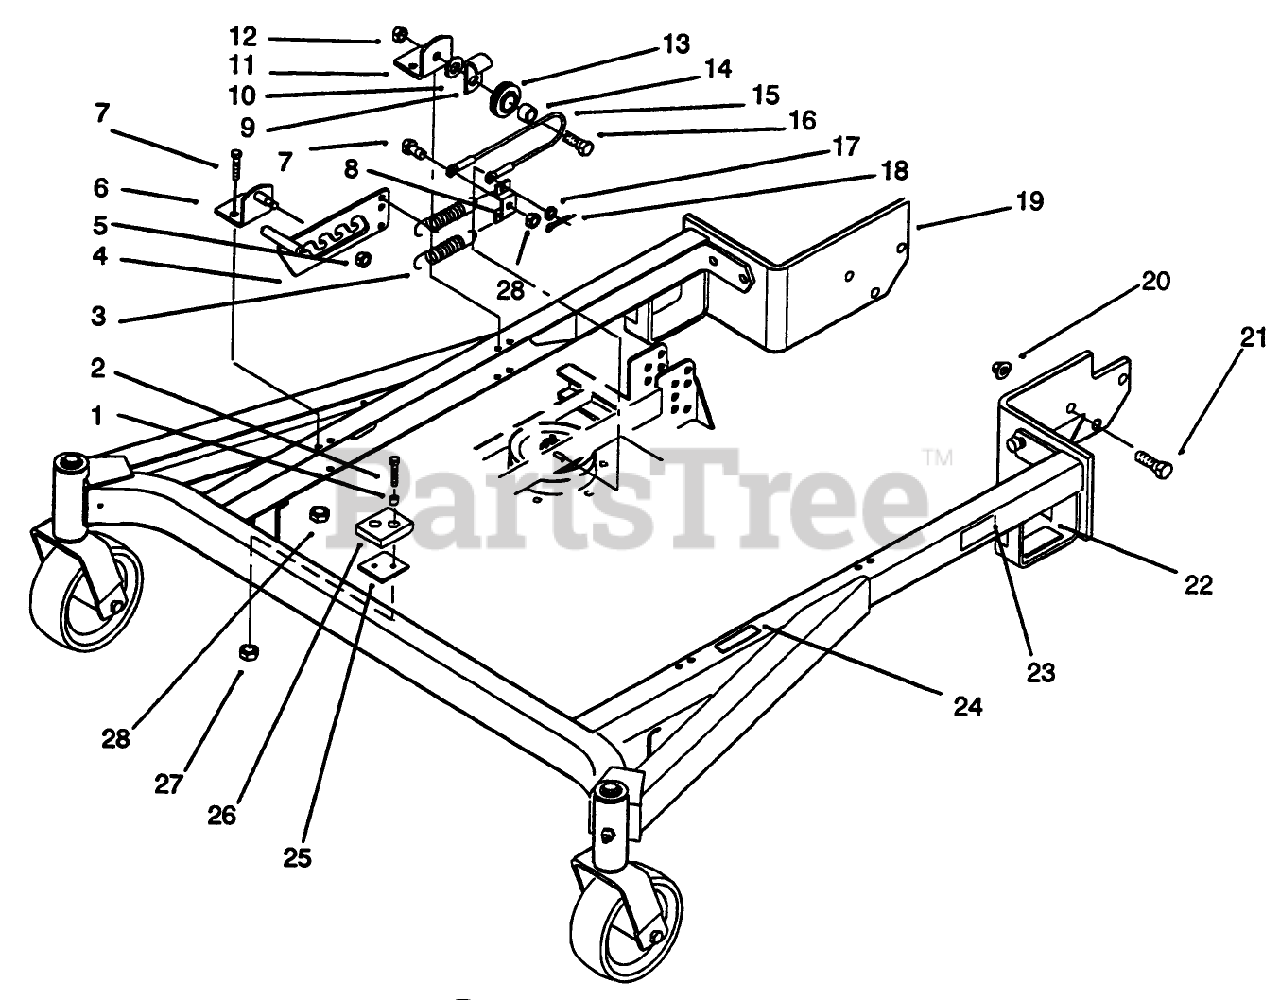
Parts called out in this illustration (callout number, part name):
1	SPACER
3	EXTENSION SPRING
4	Control-Tension
5	NUT-HF
6	Bracket-Control
7	SCREW-HH
8	SPRING BRACKET
9	CABLE RETAINER
10	THRUST WASHER
11	Bracket-Pulley
12	NUT-LOCK, NI
13	Pulley Assembly (Incl. Ref. #14)
14	BUSHING
15	CABLE
16	BOLT-SHOULDER
17	WASHER-FLAT
18	PIN-COTTER
19	Carrier Frame Assembly (Incl. Ref. #23, 24)
20	NUT-HF
21	SCREW-HHF
22	REAR RUBBER PAD
23	DECAL-HOC, LH
24	DECAL-WARNING
25	CUSHING SHIM
26	CUSHION-RUBBER
27	NUT-LOCK, NI
28	NUT-LOCK, NI
